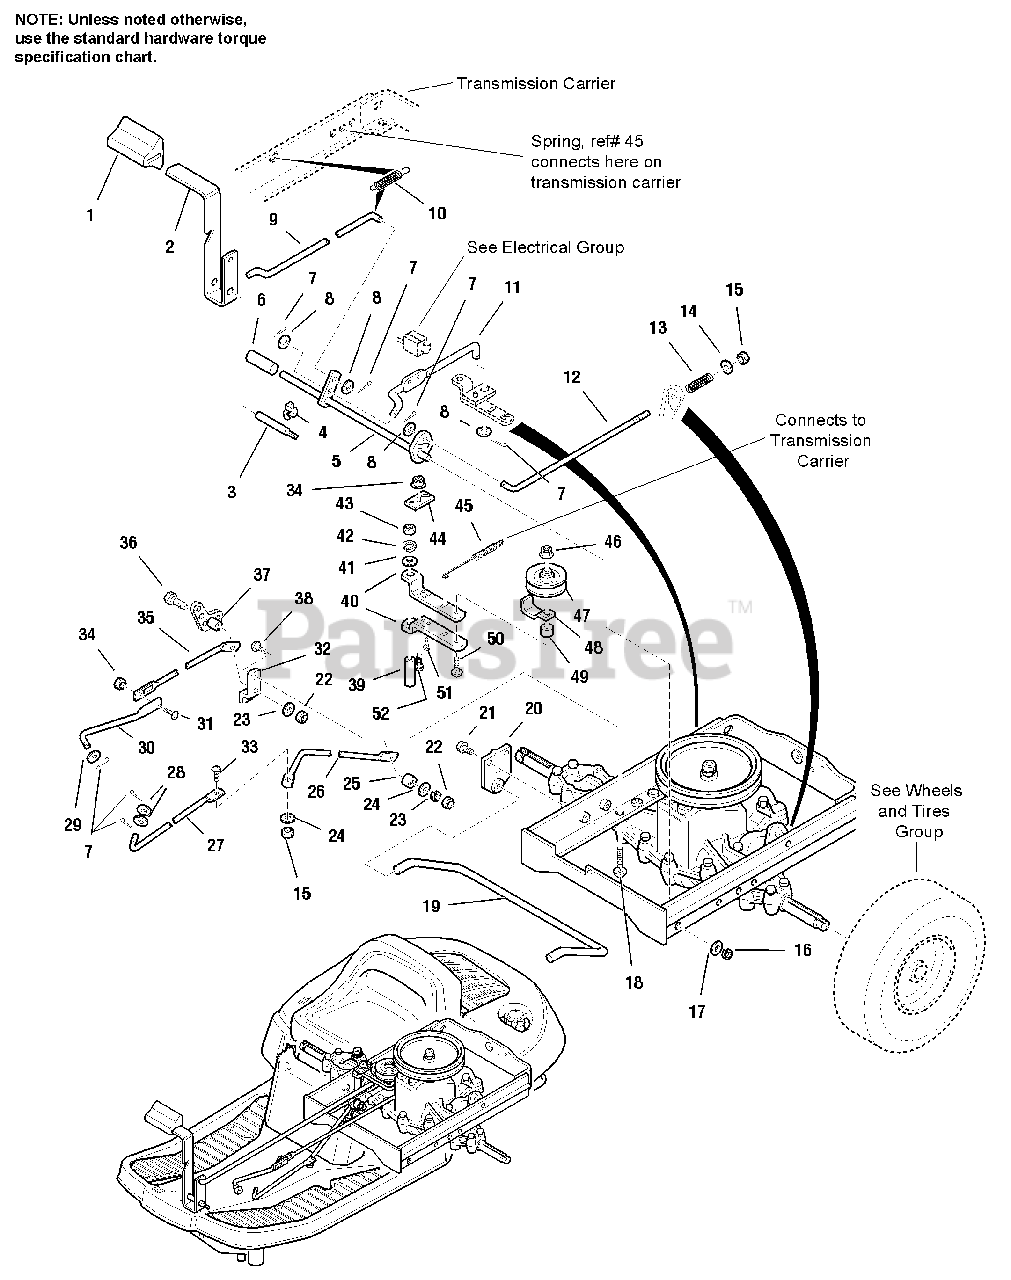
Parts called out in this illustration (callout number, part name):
1	PAD, Pedal
2	LEVER, Clutch
3	PIVOT, Brake
4	KLIP RING, 3/4
5	PIVOT SHAFT ASSY.
7	COTTER PIN, 7/64 x 3/4
8	WASHER, Plain
9	ROD, Clutch, Front
10	SPRING, Return
11	ROD, Clutch, Rear
13	SPRING, Compression
14	WASHER, 13/32 x 1-1/4 x 5/64
15	NUT, Hex, Lock, 5/16-18
16	KLIPRING, 1/2
17	WASHER, Plain
18	CARRIAGE BOLT, 5/15-18 x 2-3/4
19	TORSION BAR
20	BRACKET, Torsion Bar
21	SCREW, Taptite, 5/16-18 x 1/2
22	NUT, Hex, 5/16-18
23	LOCKWASHER, 5/16
24	WASHER, Plain, 5/16
26	ROD, Control
27	ROD, Shift, Front
28	WASHER, Plain, 1/2 x 1 x 1/32
29	WASHER, Plain, 13/32 x 7/8 x 5/64
30	ROD, Return, Front
31	CARRIAGE BOLT, 1/4-20 x 7/8
32	LEVER, Control
33	CARRIAGE BOLT, 5/16-18 X 1-1/4
34	NUT, Hex, Flange Whiz, 1/4-20
35	ROD, Return, Rear
36	CAPSCREW, 5/16-18 x 1-3/4
38	CARRIAGE BOLT, 5/16-18 X 1-1/4
39	SPACER, Pivot
40	CLEVIS, Idler Bracket
41	WASHER, Plain
42	LOCKWASHER, 5/16
43	NUT, Hex, 5/16-18
46	NUT, Hex, Jam, Lock, 3/8-16
47	PULLEY, Idler
48	GUARD, Spring
49	SPACER, 25/64 x 5/8 x 11/16
50	CARRIAGE BOLT, 3/8-16 x 2-1/4
51	SCREW, Taptite, 1/4-20 x 5/8
52	CAPSCREW, Hex, 1/4-20 x 3/4
